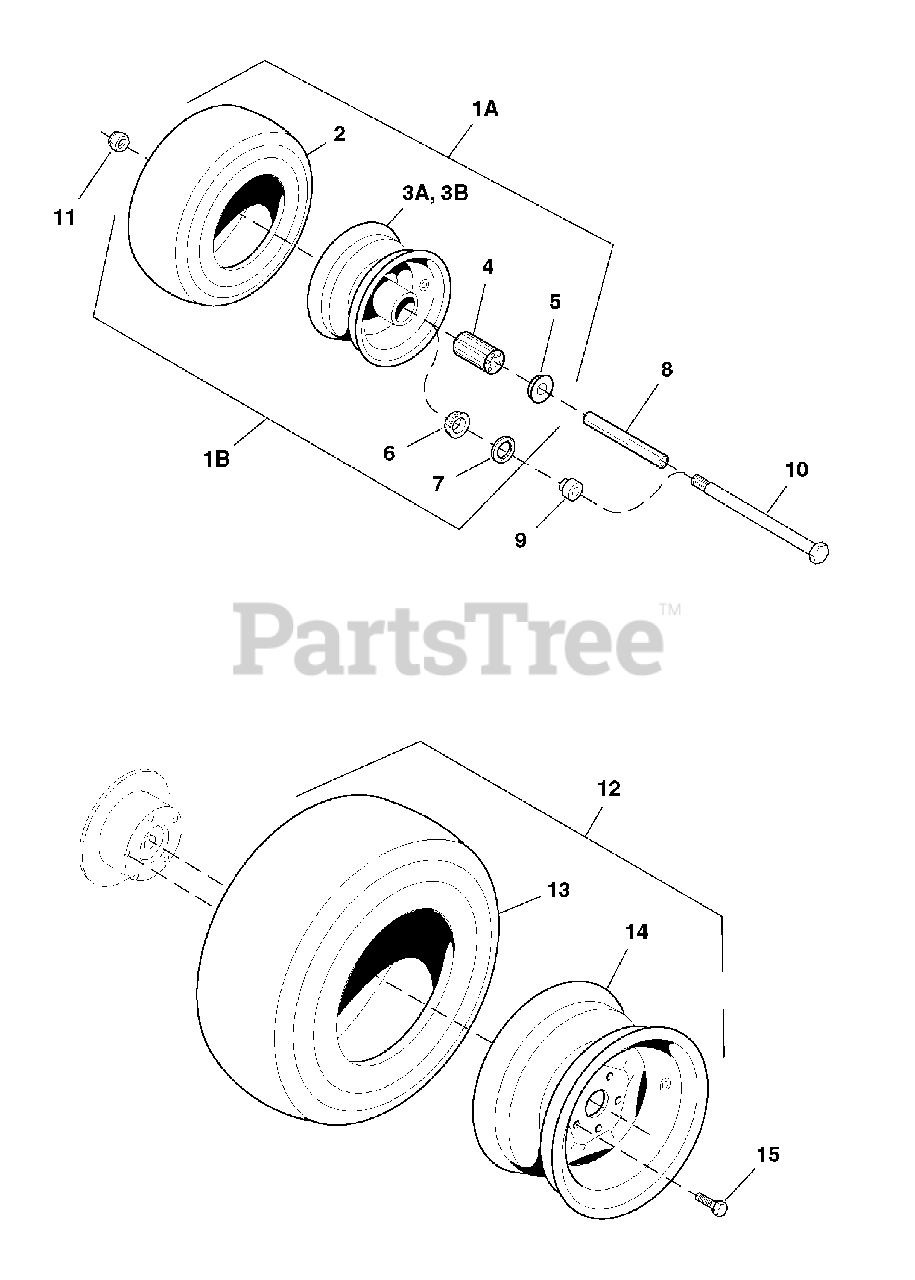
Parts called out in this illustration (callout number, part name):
1A	WHEEL & TIRE ASSEMBLY, Front, 13 x 5.0 x 6, Complete (Includes Ref 2, 3A, 4 & 5) (for serial no. 101-200)
1B	WHEEL & TIRE ASSEMBLY, Front, 13 x 5.0 x 6, Complete
2	TIRE, Front, 13 x 5.0 x 6
3A	WHEEL ASSEMBLY, Front, for 13 x 5.0 x 6 Tires, Complete (Includes Ref 4 & 5) (for serial no. 101-200)
3B	WHEEL ASSEMBLY, Front, for 13 x 5.0 x 6 Tires, Complete
4	BEARING, Roller (2 per tire)
5	RETAINER, Bearing (2 per tire)
6	BEARING, TAPERED CONE
7	SEAL, GREASE
8	AXLE, Front Caster (for serial no. 101-200)
9	ADAPTER, Caster Wheel (2 per tire) (for serial no. 201 & up)
10	CAPSCREW, Hex Hd, 1-2/13 x 7-1/2
11	NUT, Hex, Nylon Lock, 1-2/13
12	WHEEL & TIRE ASSEMBLY, Rear, 23 x 10.5 x 12, Complete (Includes Ref 10 & 11)
13	TIRE, Rear, 23 x 10.5 x 12
14	WHEEL ASSEMBLY, Rear, for 23 x 10.5 x 12 Tires
15	WHEEL LUG, 1/2 x 1-5/8
